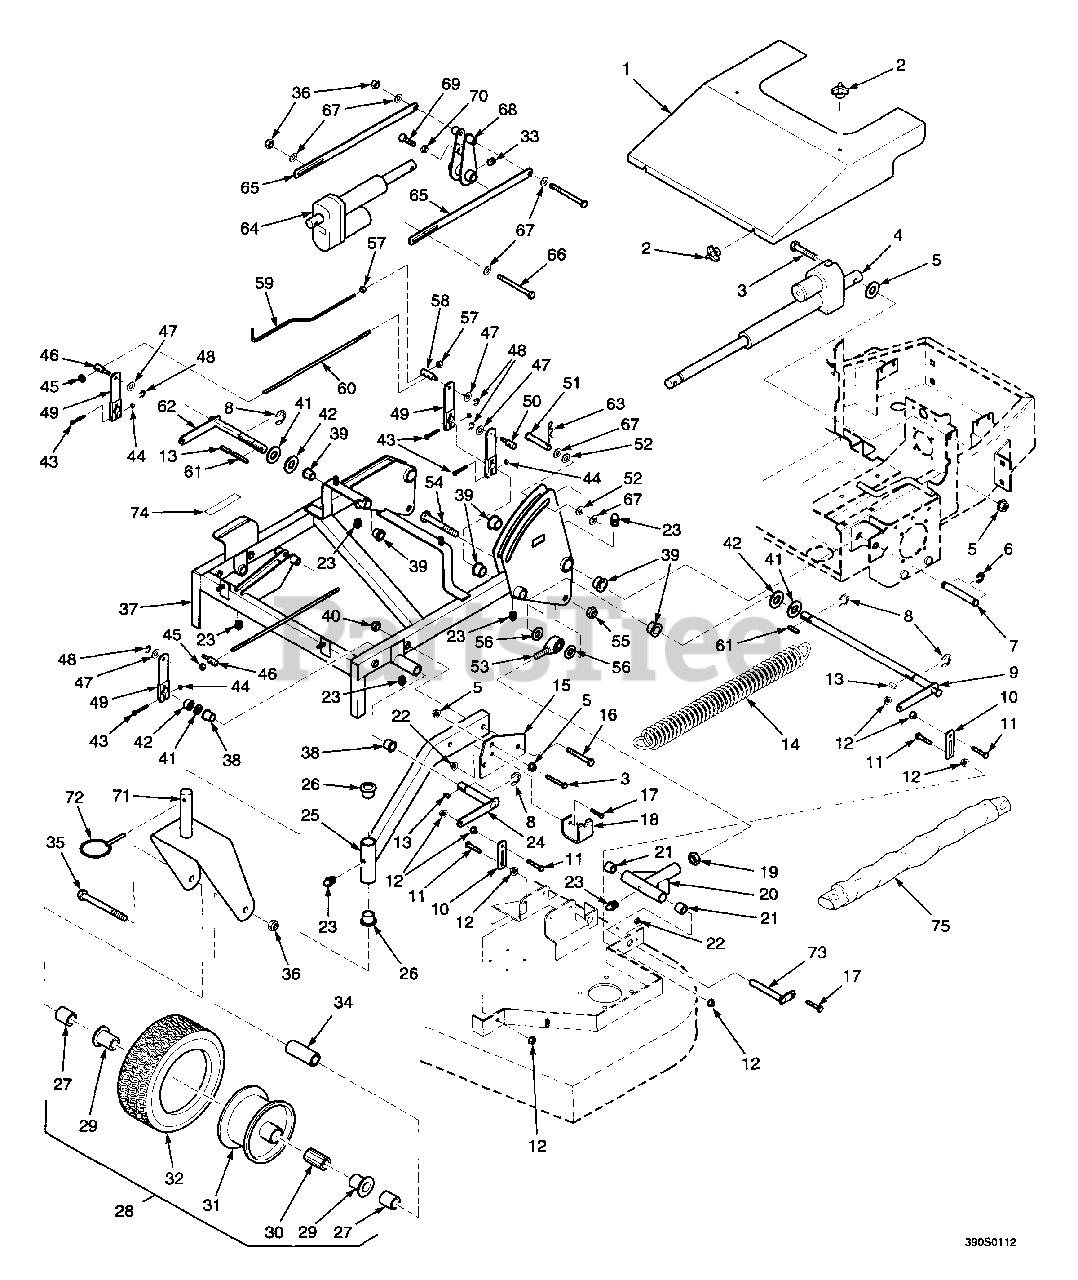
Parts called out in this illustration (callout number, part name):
1	Cover, Belt
2	Wingnut, Plastic, 3/8-16
3	Bolt, Hex Head, 1/2-13 x 2-1/2
4	Actuator, Deck Lift
5	Serr. Fl. Hex Nut, 1/2-13
6	Retaining Ring, 1.125 Ext
7	Pin, Deck support Mounting
8	Retaining Ring, 1.00 Ext "E"
9	Lift Bellcrank, LH Rear
10	Link, Deck Support
11	Bolt, Hex Head, 7/16-14 x 1-3/4
12	Serr. Fl. Hex Nut, 7/16-14
13	Key, 1/4 x 1/4 x 3/4
14	Spring, Deck Lift
15	Anchor, Deck Spring
16	Bolt, Hex Head, 5/8-11 x 5-1/2
17	Serr. Fl. Hex Head CPSCR, 5/16-18 x 3/4
18	Retainer, Spring
19	Hex Nut, 3/4-16
20	Push Rod Assy
21	Bushing, Oilite - 3/4 ID
22	Serr. Fl. Hex Nut, 5/16-18
23	Grease Fitting
24	Lift Bellcrank, Front
25	Tube, LH Caster
26	Bushing, Oilite - 1.00 ID
27	Spacer
28	Wheel Assembly, Caster
29	Retainer
30	Bearing, Roller
31	Rim
32	Tire
33	Setscrew, Hex Socket, 5/16-18 x .75
34	Sleeve, Caster Wheel
35	Bolt, Hex Head, 1/2-13 x 6-1/2
36	Hex Locknut, Elastic Stop, 1/2-13
37	Frame, Deck Support
38	Bushing, Oilite - 1-1/8 ID
39	Bushing, Oilite - 1.00 ID
40	Hex Locknut, Elastic Stop, 5/8-11
41	Flatwasher, 1" (1.062 x 1.75 x .10)
42	Spacer
43	Bolt, Hex Head, 3/8-16 x 2
44	Hex Locknut, Elastic Stop, 3/8-16
45	Hex Nut, 5/8-11
46	Swivel Joint, RH
47	Flatwasher, 5/8 (.656 x 1.312 x .095)
48	Retaining Ring, 5/8 Ext "E"
49	Lever, Deck Lift
50	Swivel Joint, LH
51	Pin, Clevis, 1/2 x 2.25
52	Flatwasher, Nylon, 1" (.54 x 1.125 x .25)
53	Rod End, Male, 3/4-16 RH
54	Bolt, Hex Head, 3/4-16 x 3
55	Hex Locknut, Elastic Stop, 3/4-16
56	Spacer
57	Hex Nut, 3/8-16
58	Swivel Joint, LH
59	Rod, Height Indicator
60	Stud, Mower Lift
61	Key, 1/4 x 1/4 x 1-1/4
62	Lift, Bellcrank, RH Rear
63	Cotter Pin, Hair - 0.94 x 1.62
64	Actuator, Cutting Height
65	Link, Deck Travel Limit
66	Bolt, Hex Head, 1/2-13 x 4-3/4
67	Flatwasher, 1/2 (.531 x 1.06 x .095)
68	Lever, Bellcrank Actuation
69	Bolt, Hex Head, 1/2-13 x 2
70	Hex Nut, 1/2-13
71	Yoke, Caster Wheel
72	Quick Pin
73	Shaft, Push Rod
74	Decal, Cutting Height
75	Cover, Spring
